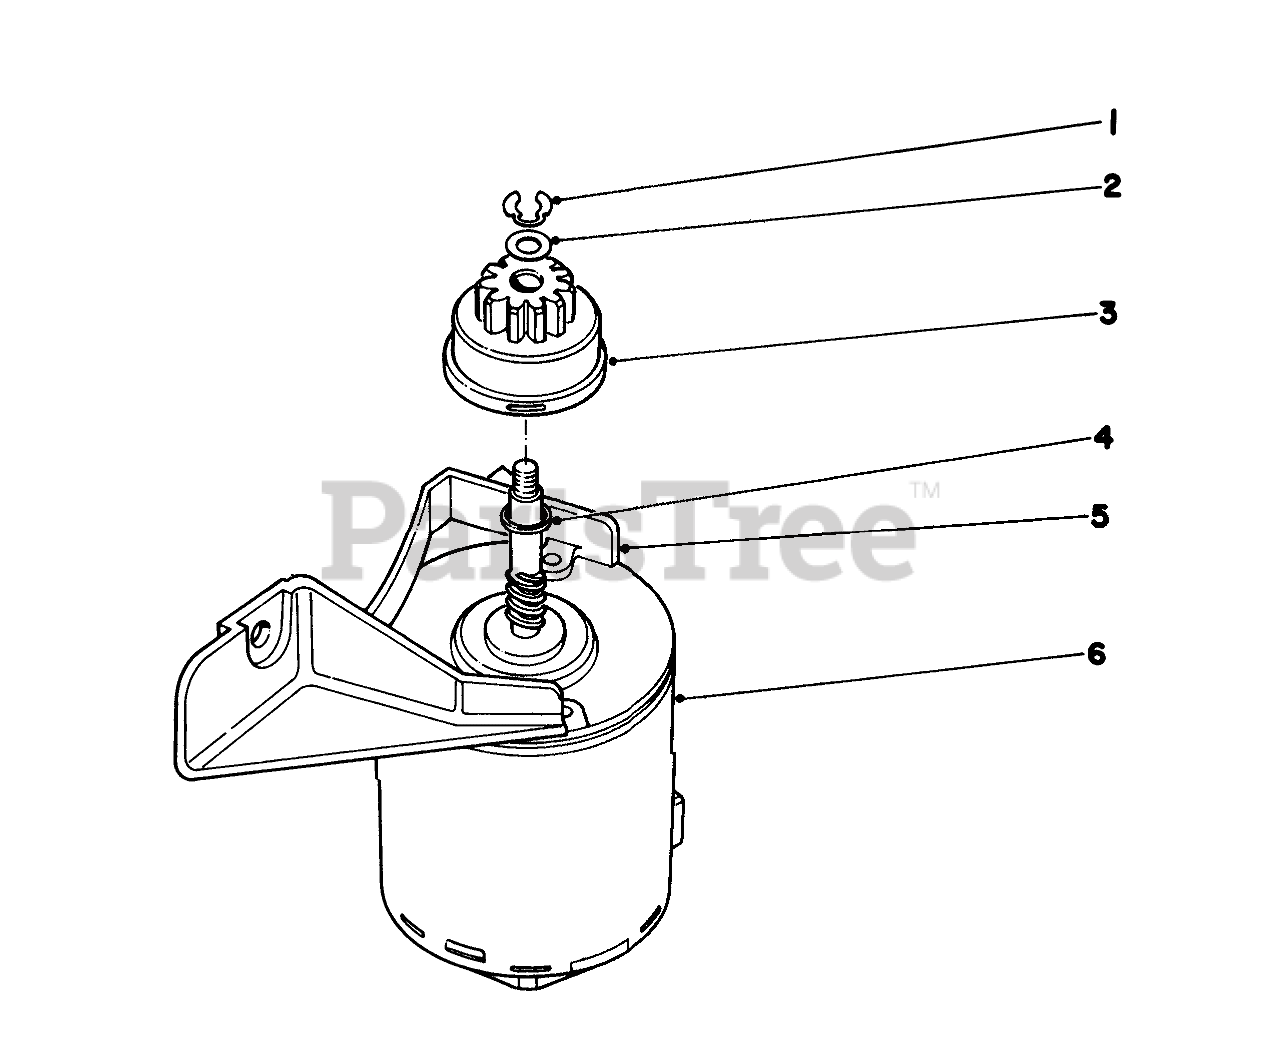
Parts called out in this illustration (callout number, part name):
1	RING-RETAINING
2	WASHER
3	PINION ASM
4	Spacer
5	Mounting Bracket
6	Starter Motor
